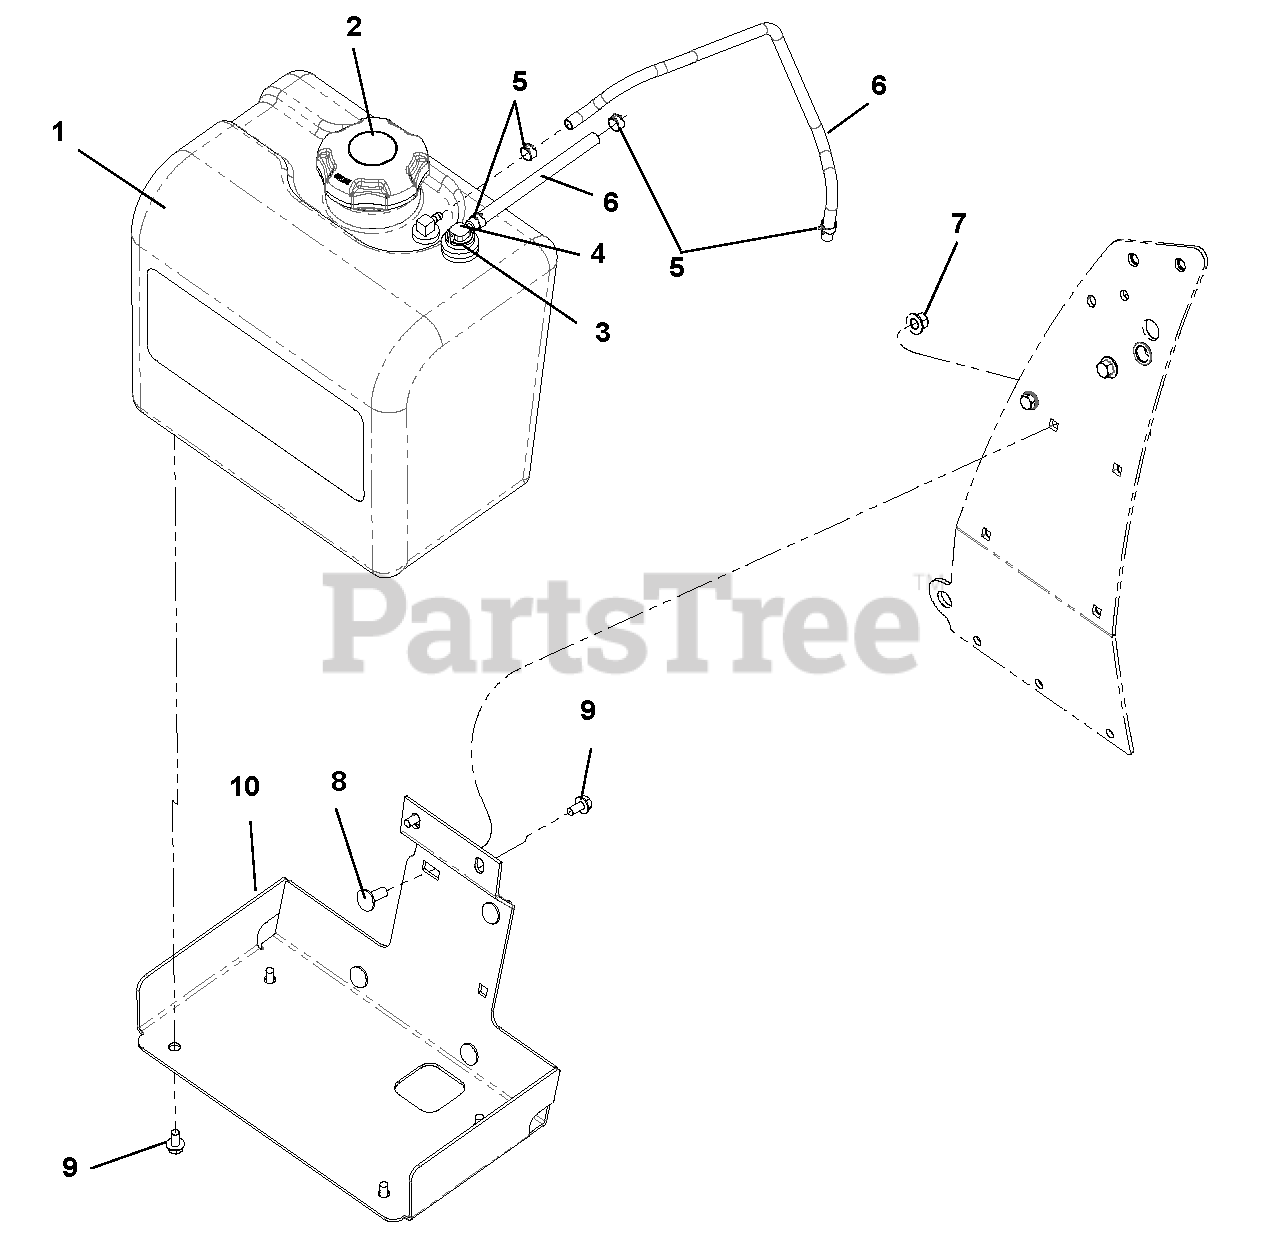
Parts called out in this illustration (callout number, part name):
1	ASSM, ARIENS EPA FUEL TANK
2	CAP,3.50" VENT-IN RATCHET FUEL
3	GROMMET, DAPCO VITON #12240
4	FUEL PICKUP
5	CLAMP, FUEL LINE
6	HOSE, .25 LOW-PERM BULK GAS
7	@NUT-LK-NYL .38-16 YWZC
8	@BLT-RDHDSHSQNK.38-16X1.0 G5YZ
9	SCR-HEX-FL M8X1.25X16 10.9
10	BRACKET, FUEL TANK MOUNTING
